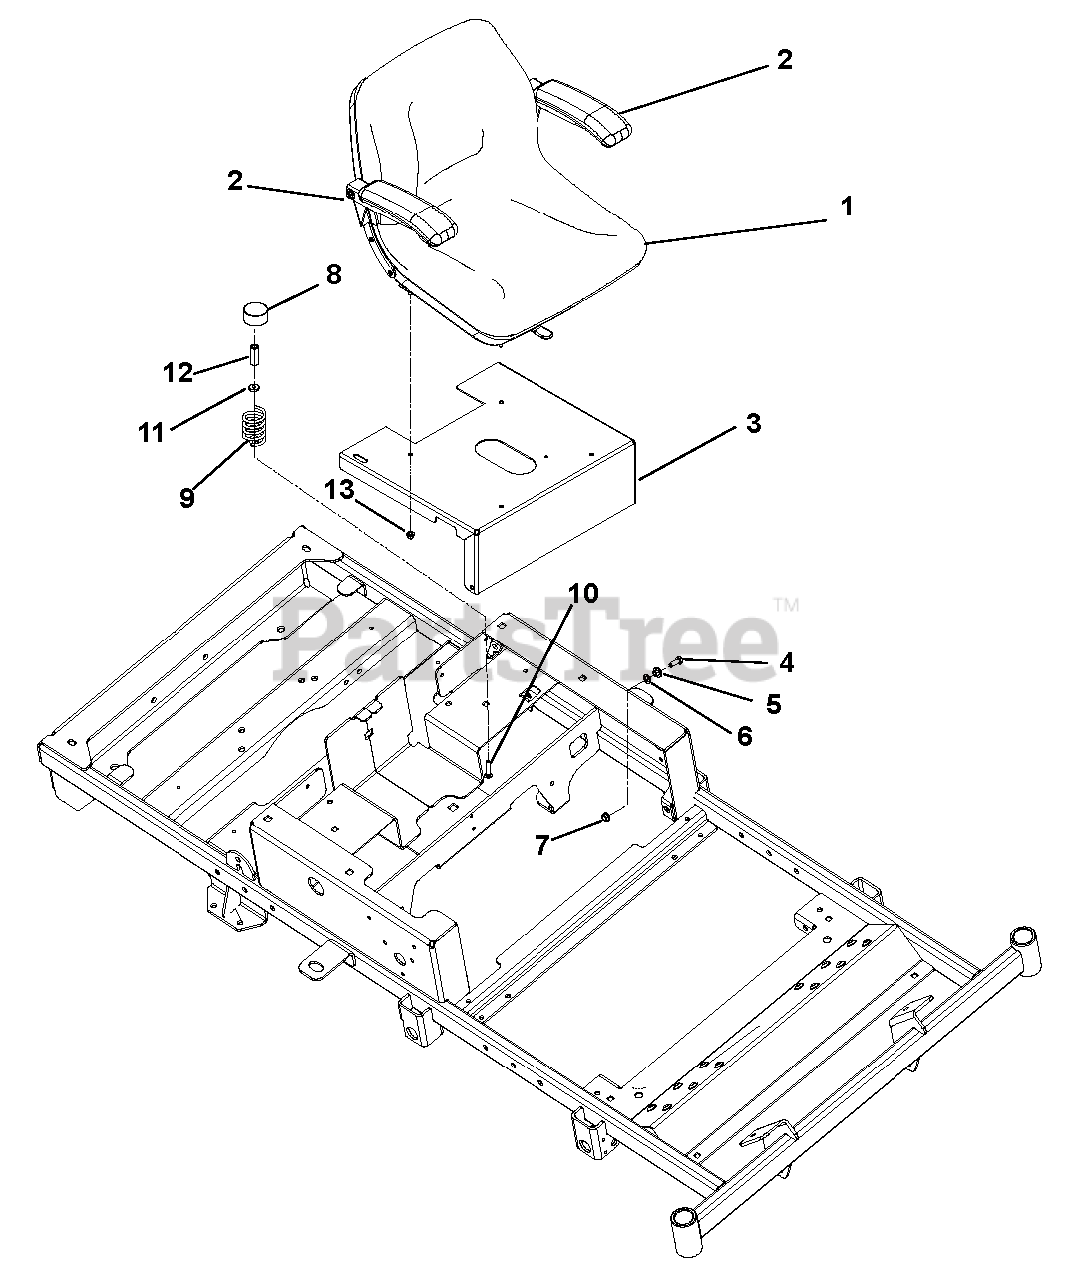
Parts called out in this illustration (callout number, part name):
1	Seat with Arm
2	Arm Rest Kit
3	Seat Plate
4	Bolt, Hex .38-16 x 1.00 Grade 5
5	Bushing, Flange .385 x .500 x .875 x .406
6	Washer, Flat Steel .52 x .827 x .062
7	Nut, .38-16 Nyloc Flange
9	Spring, Seat
10	Bolt, Round Head Square Neck .31-18 x 1.50 Grade 5
11	Washer, Flat Steel .328 x .87 x .179
12	Nut, Coupling 5/16-18 x 1 .75
13	Nut, 5/16-18 Flange Nyloc
